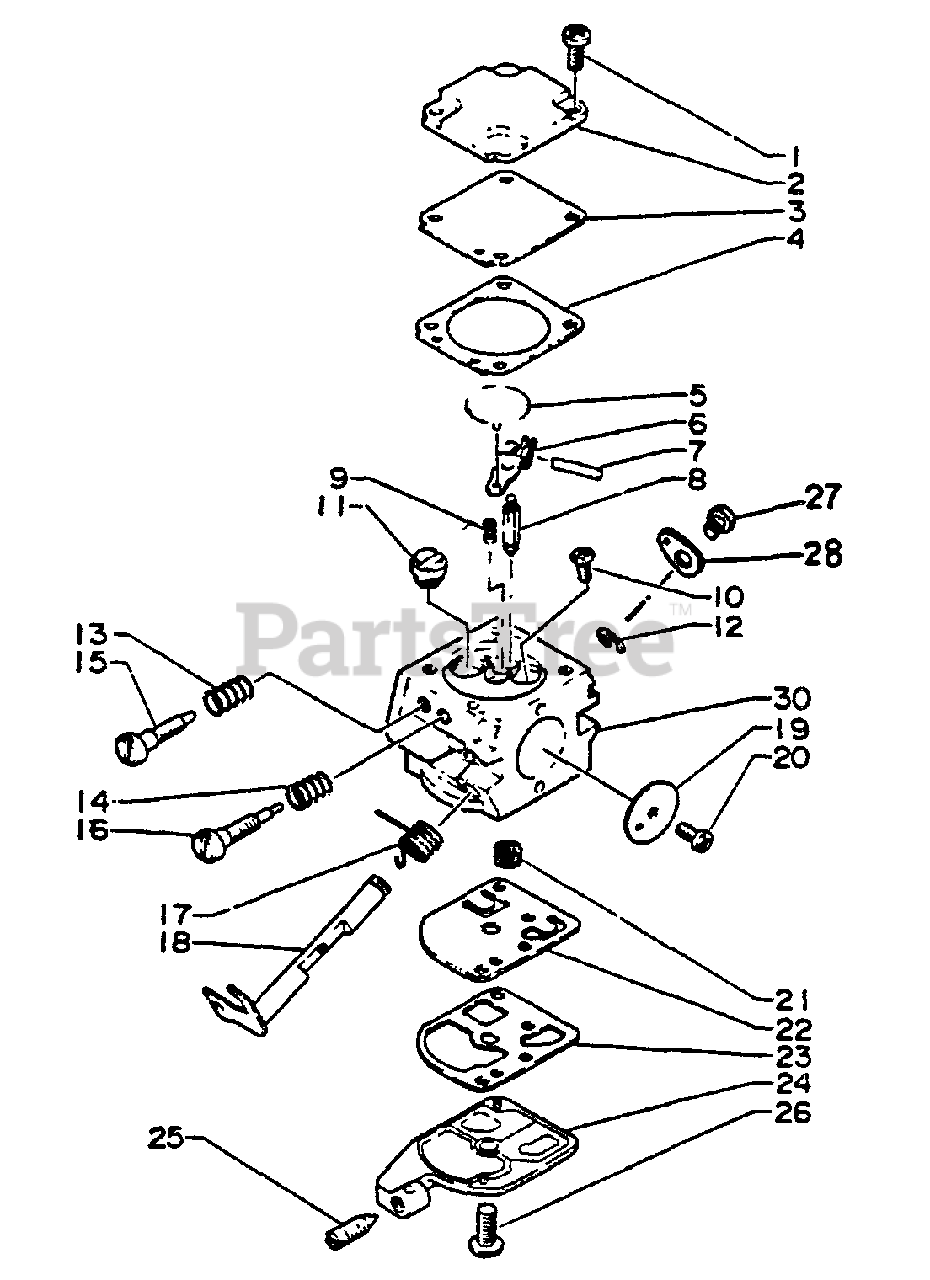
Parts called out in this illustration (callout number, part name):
1	SCREW
2	COVER, DIAPHRAGM
3	DIAPHRAGM
4	GASKET, METERING
5	DISK
6	LEVER, METERING
7	PIN, METERING LEVER
9	SPRING, METERING LEVER
15	NEEDLE, HIGH SPEED
16	NEEDLE, IDLE
17	SPRING, THROTTLE RETURN
18	SHAFT, THROTTLE
19	VALVE, THROTTLE
20	SCREW
21	STRAINER
24	BASE, PUMP
25	SCREW, IDLE ADJUST
28	LEVER, THROTTLE
